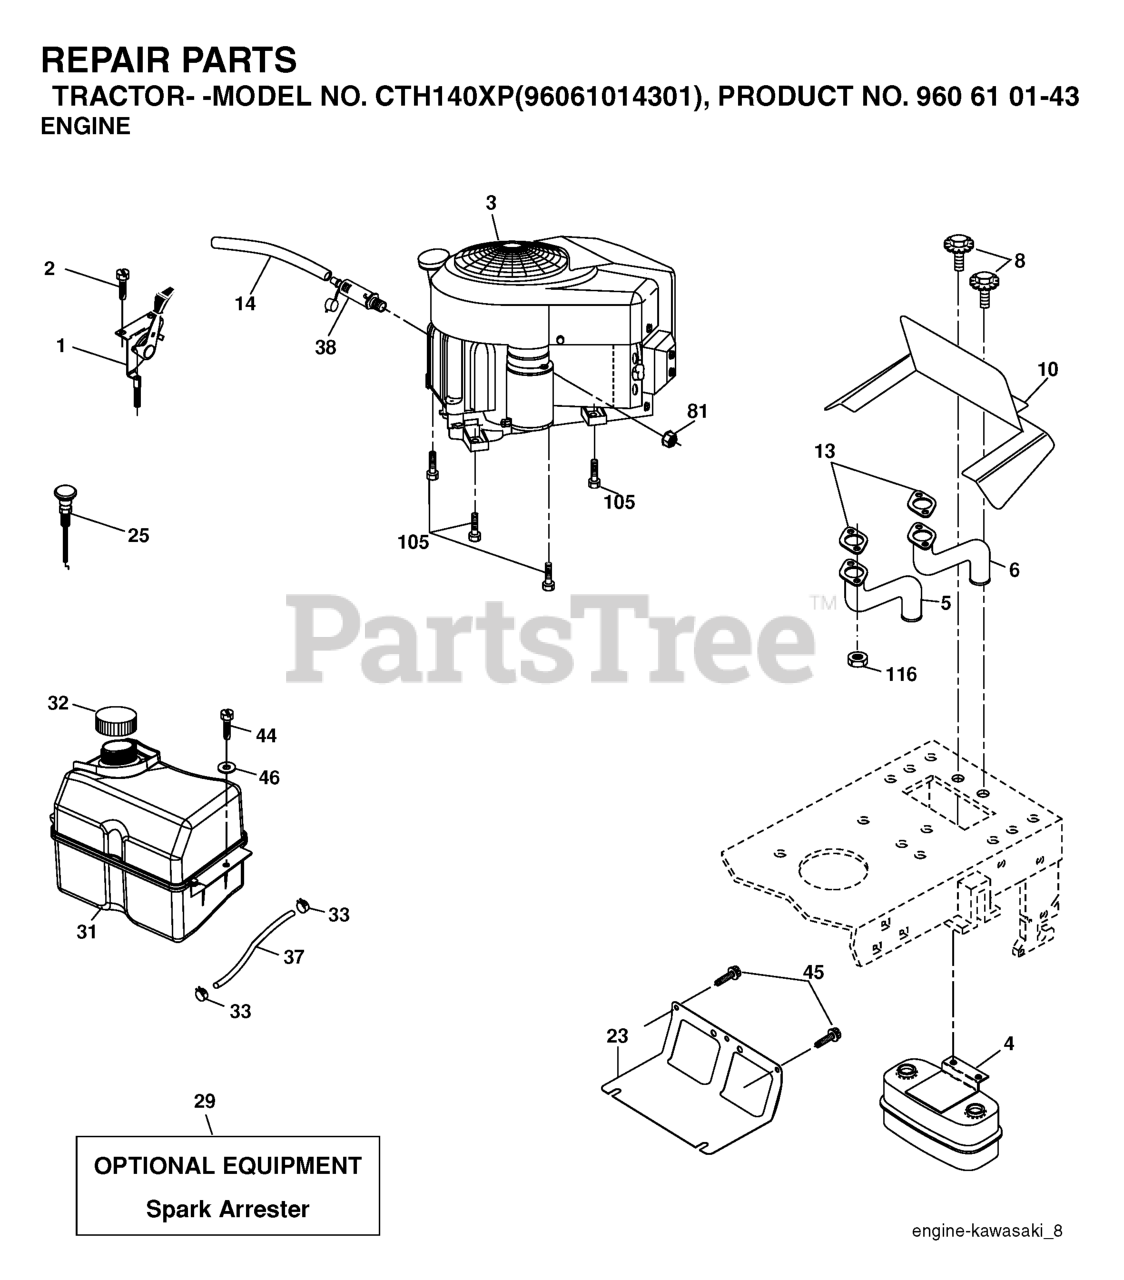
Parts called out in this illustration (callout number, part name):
1	CONTROL, THROTTLE
2	SCREW
4	MUFFLER.TWIN.CYL.LOW.TONE
5	EXHAUST TUBE LH KAWI
6	EXHAUST TUBE RH KAWI
8	BOLT.5/16-18UNCX3/4 W/SEMS.BLK
10	RP SHIELD HEAT MUFFLER
14	TUBE, DRAIN OIL ASM.
23	SHIELD.BROWNING.DBR.GUARD
29	KIT.SPARK ARRESTOR 794945 B&S
31	TANK FUEL
32	FUEL CAP
33	HOSE CLAMP
37	LINE.FUEL.20
44	SCREW HEXWSHR 1/4-20X3/4
45	SCREW, 3/8-16X3/4
81	NUT
105	SCREW 3/8-16X1
116	NUT.HEX.FLANGE.TOPLOCK
